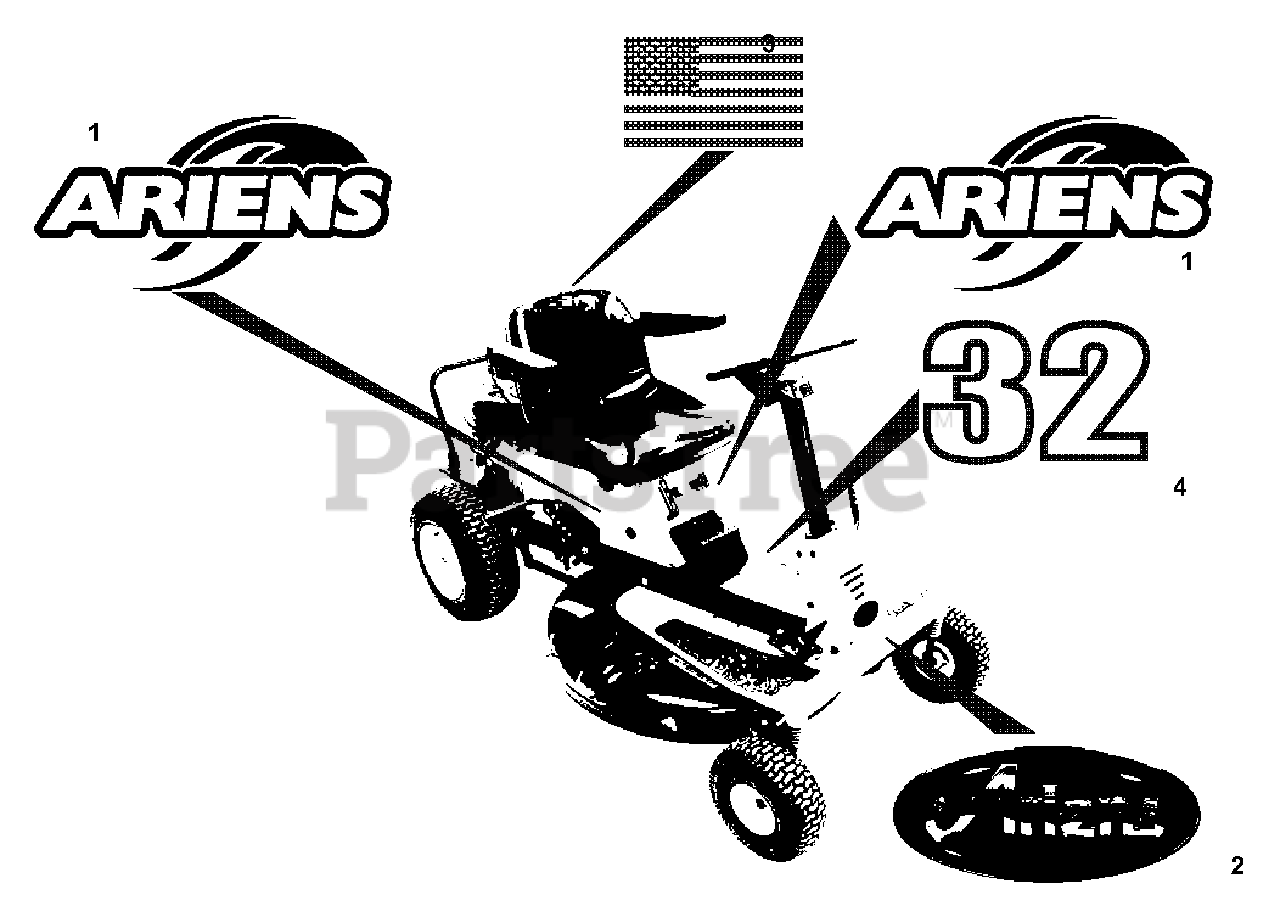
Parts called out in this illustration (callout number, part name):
1	DECAL-ARIENS ZOOM
2	DECAL-ARIENS JEWEL
3	DECAL, AMERICAN FLAG
4	DECAL, 28
4	DECAL, 32
